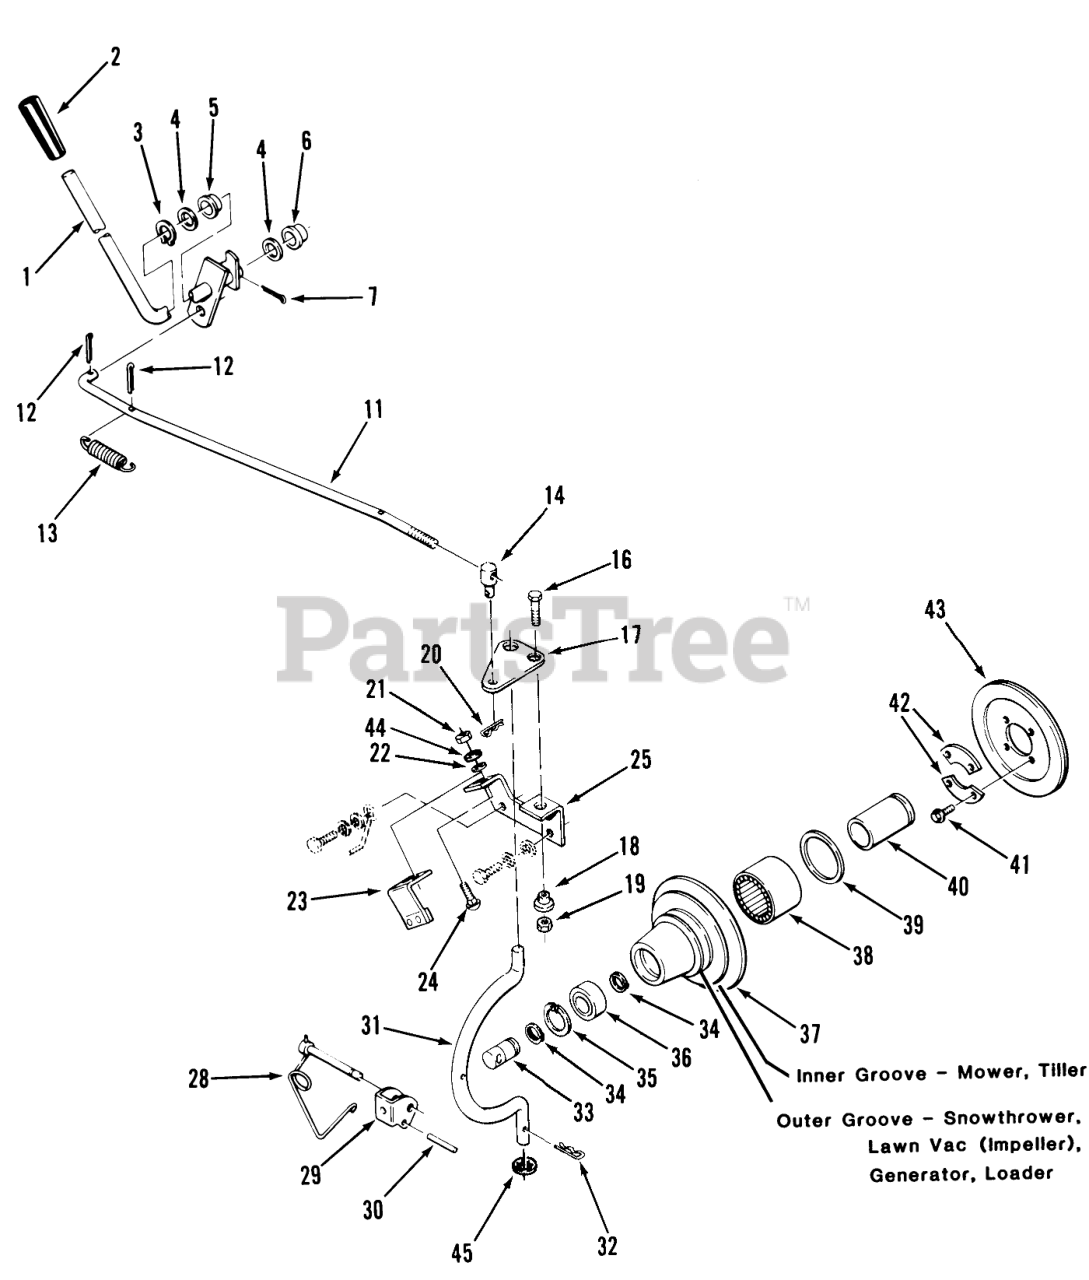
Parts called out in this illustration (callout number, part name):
1	PTO Clutch Lever
2	GRIP
3	Grip Ring
4	SHIM-WASHER
5	BUSHING-NYLINER
6	NYLINER BUSHING
7	Pop Rivet
11	PT0 Clutch Rod
12	Pop Rivet
13	SPRING
14	TRUNNION
16	BOLT
17	PLATE R
18	SPACER-LIFT LINK
18	SPACER-BRAKE LINK
19	Nut
20	Hairpin Cotter
21	Nut
23	ASSY-BRAKE
23	PTO Brake Assy
24	Carriage Bolt 1/4-20 x 1
25	BRACKET-ENGINE B
28	Pin
29	Clevis
31	ROD-HOUSING
31	ROD-HOUSING (NS)
32	Hairpin
33	SHAFT-PTO
34	RING-SNAP, EXTERNAL
35	Ring-Snap
36	BEARING-BALL
37	Housing-Clutch
38	BRG-NEEDLE OPEN END
39	SEAL-OIL
40	BEARING RACE
41	H H C S
42	RETAINER
43	Clutch Plate & Facing
44	Washer
45	RING-REINFORCED CIRC
